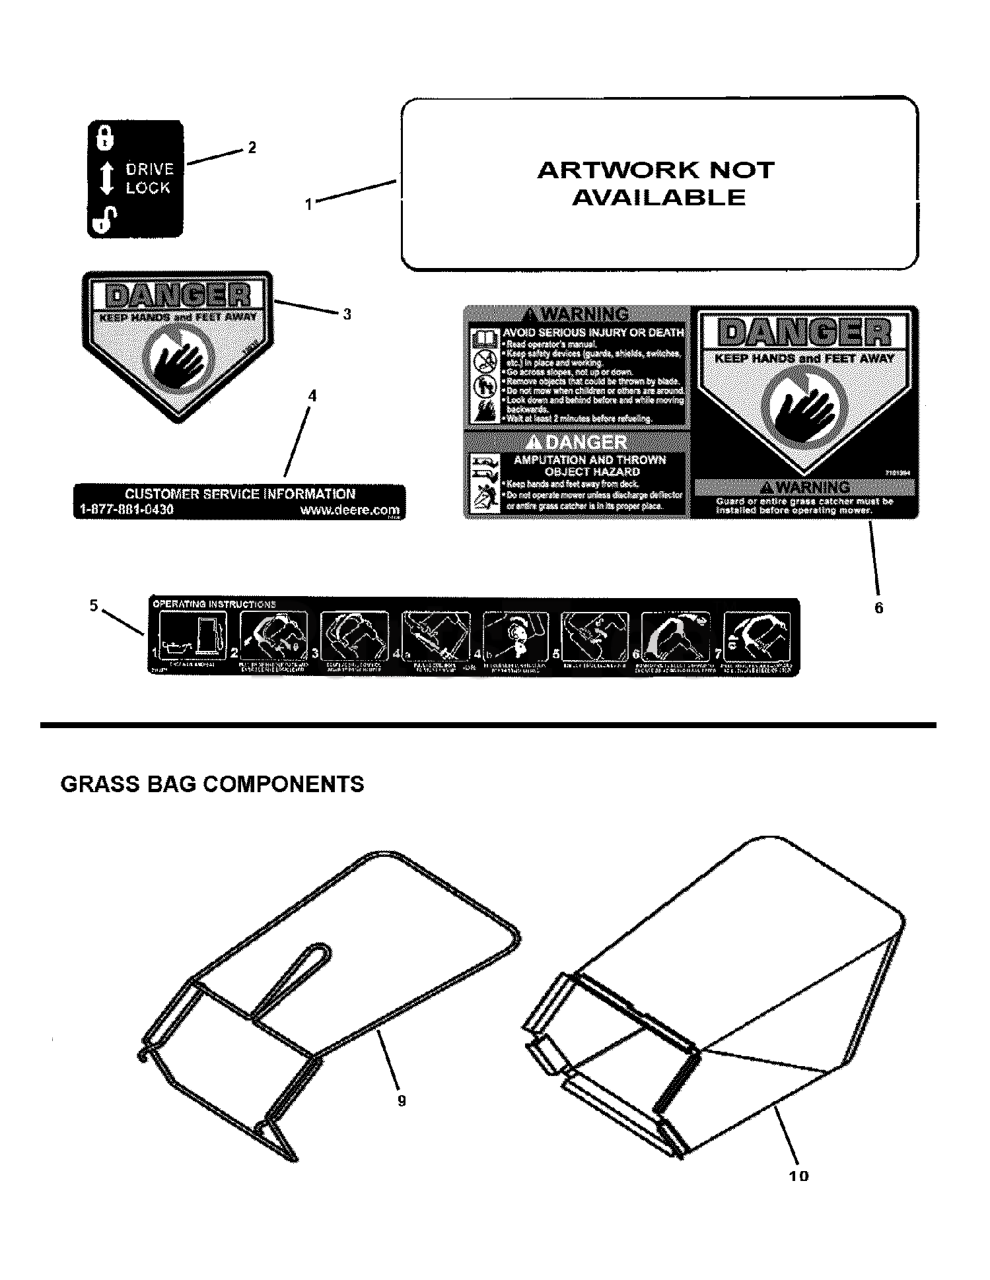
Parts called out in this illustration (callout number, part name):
1	DECAL, JS26 MOWMENTUM
2	DECAL, NEUTRAL LOCK
3	DECAL, DANGER, CUT FINGER
4	DECAL,CUSTOMER SERVICE,MY08,DEERE
5	DECAL, OPERATION, JD
6	DECAL, WARNING, REAR DISCHARGE DOOR
9	BAG FRAME, RD
10	BAG, GRASS, 22" REAR DISCHARGE
